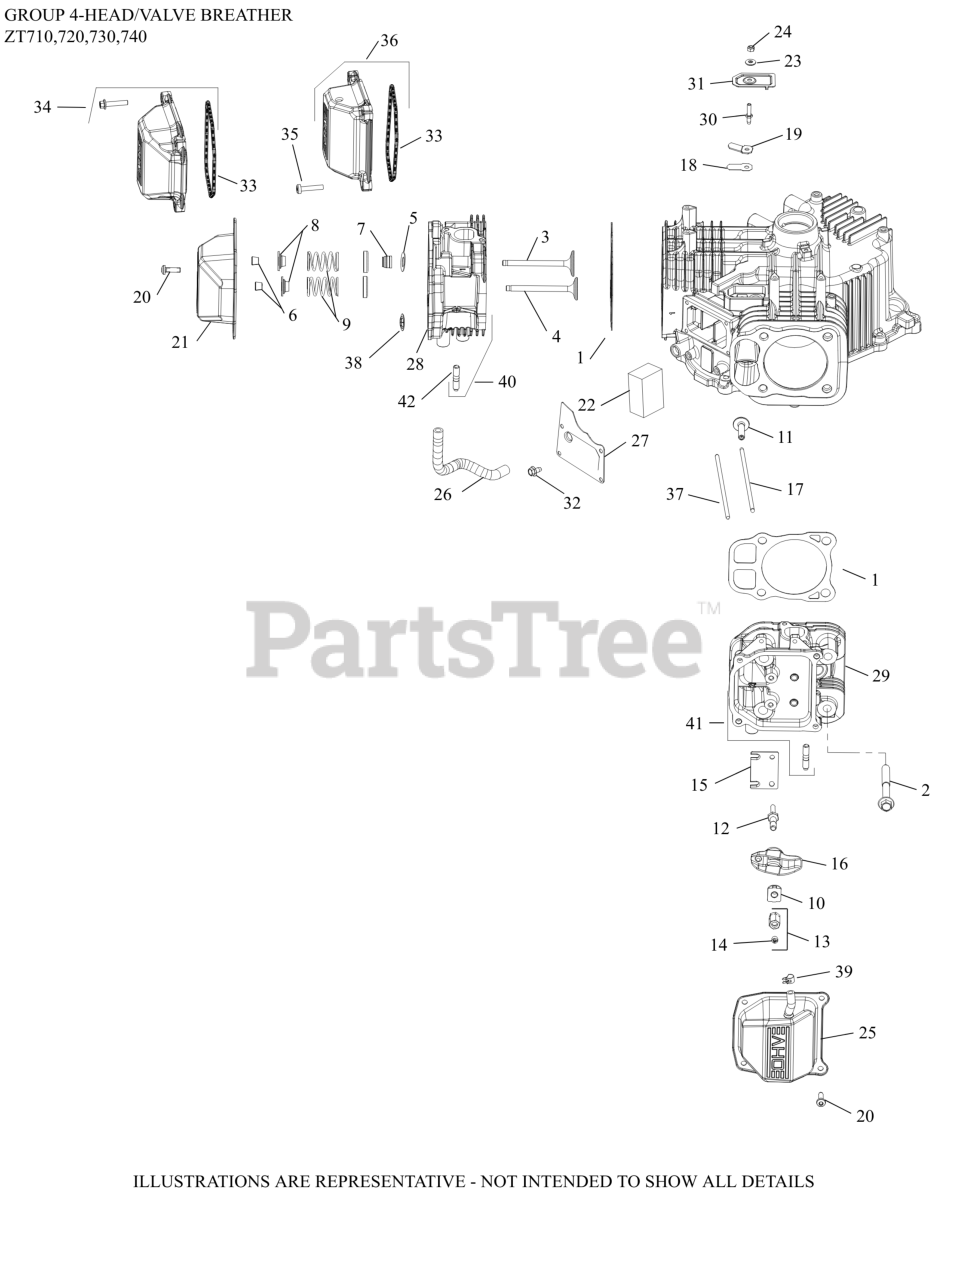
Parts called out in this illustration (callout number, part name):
1	KIT, GASKET CYLINDER HEAD
2	SCREW, FLG M10X1.5X90
3	VALVE, INTAKE
3	VALVE, INTAKE (.25) - (#2401702S)
4	VALVE, EXHAUST
4	VALVE, EXHAUST (.25)
5	SPACER (.010")
6	KIT, RETAINER
7	SEAL, VALVE BAND
8	CAP, VALVE SPRING
9	SPRING VALVE
10	PIVOT, ROCKER ARM
12	STUD, ROCKER
13	HEX NUT ASSEMBLY
14	SCREW, SET
15	PLATE, GUIDE
16	ARM, ROCKER
17	ROD, PUSH
18	REED, BREATHER
19	RETAINER, REED
22	FILTER, BREATHER
23	WASHER, SEALING
24	NUT, LOCK M5X.8
26	HOSE, BREATHER
27	COVER, BREATHER MEDIA
31	COVER, BREATHER REED
33	O-RING (YELLOW), VALVE CO
34	KIT, VALVE COVER-PLAIN (PLASTIC)
35	SCREW, PAN HEAD
36	KIT,BREATHER VALVE COVER (PLASTIC)
38	RETAINER, VALVE GUIDE (KM)
